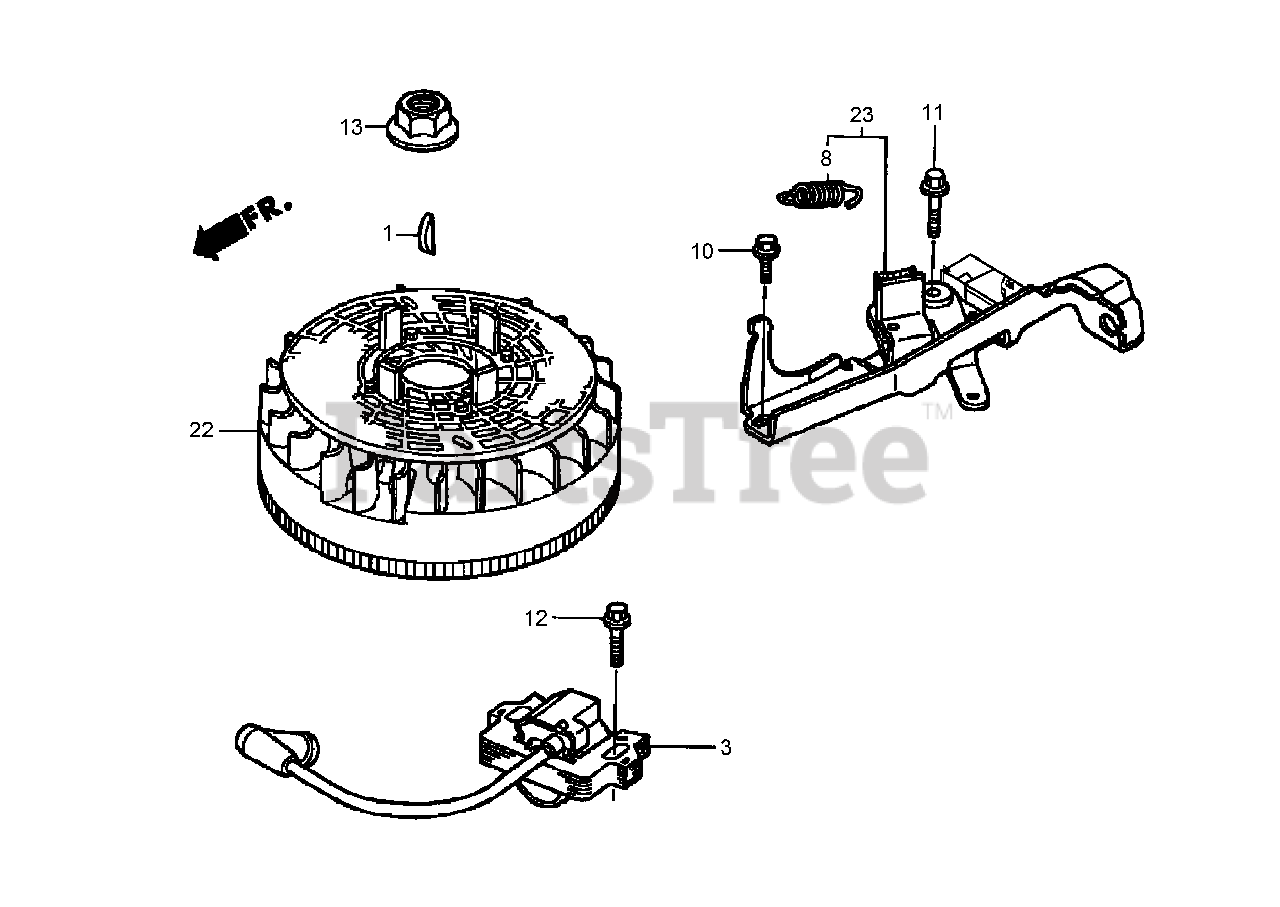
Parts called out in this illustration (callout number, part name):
1	KEY-WOODRUFF (25X18)
3	IGNITION COIL ASM
8	SPRING-LEVER, BRAKE
10	BOLT-FLANGE (6X14)
11	BOLT-FLANGE (6X23) (CT200)
12	BOLT-FLANGE (6X20)
13	NUT (14MM)
22	FLYWHEEL ASM
23	BRAKE SUB-ASM
